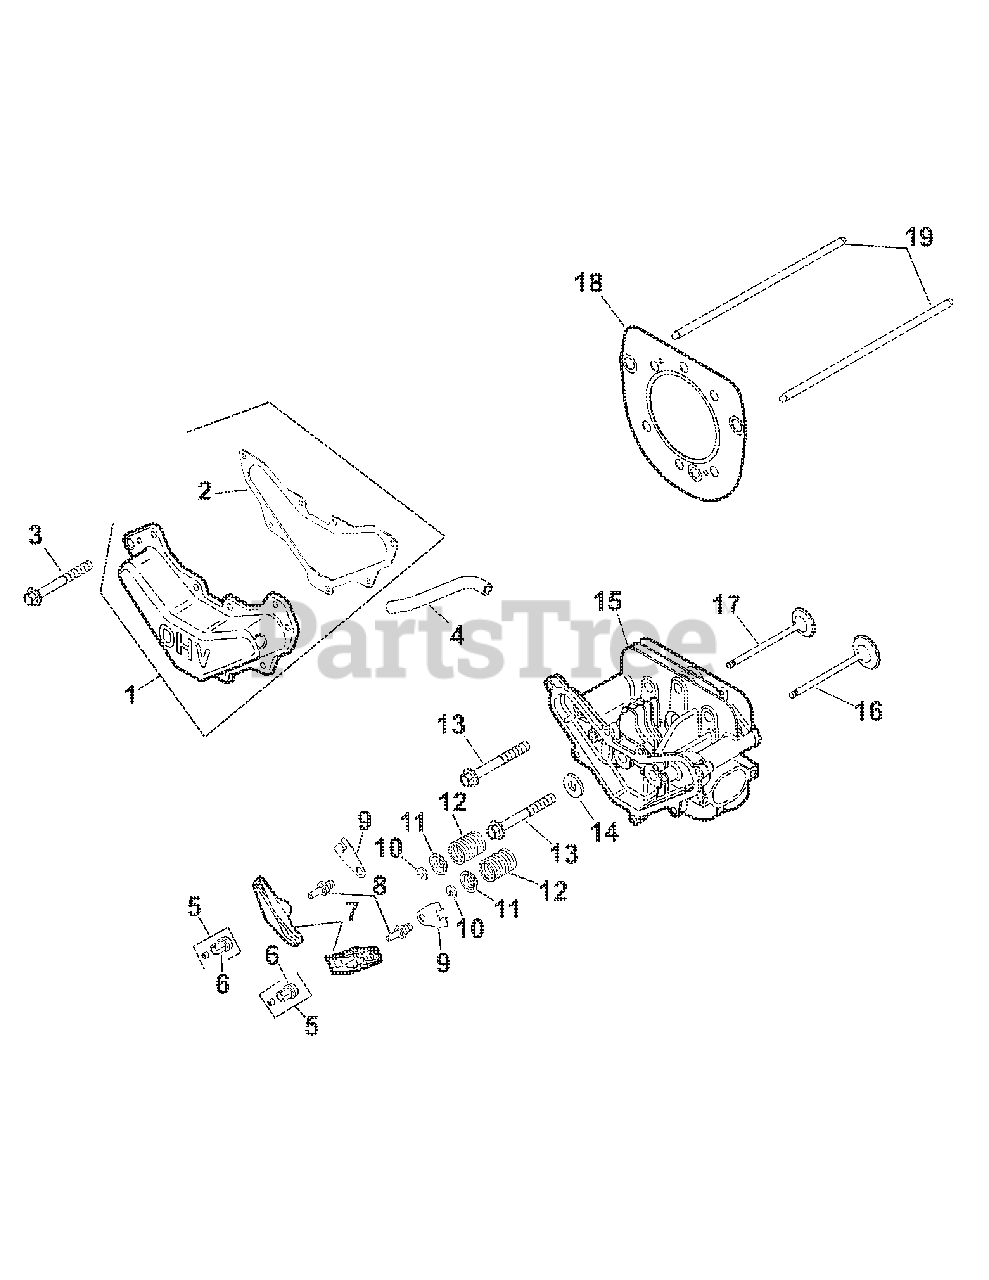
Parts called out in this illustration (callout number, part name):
1	Valve Cover Kit
2	Valve Cover Gasket
3	Hex Flange Screw (M6 x 1.0 x 20)
4	Breather Hose
5	Rocker Arm Pivot Kit
8	Rocker Pivot Set Screw
9	Push Rod Guide Plate
11	Valve Spring Cap
13	Hex Flange Screw (M10 x 1.5 x 37)
14	1/2" Flat Washer
15	Cylinder Head
16	Exhaust Valve
18	Cylinder Head Gasket Repair Kit
19	Push Rod
